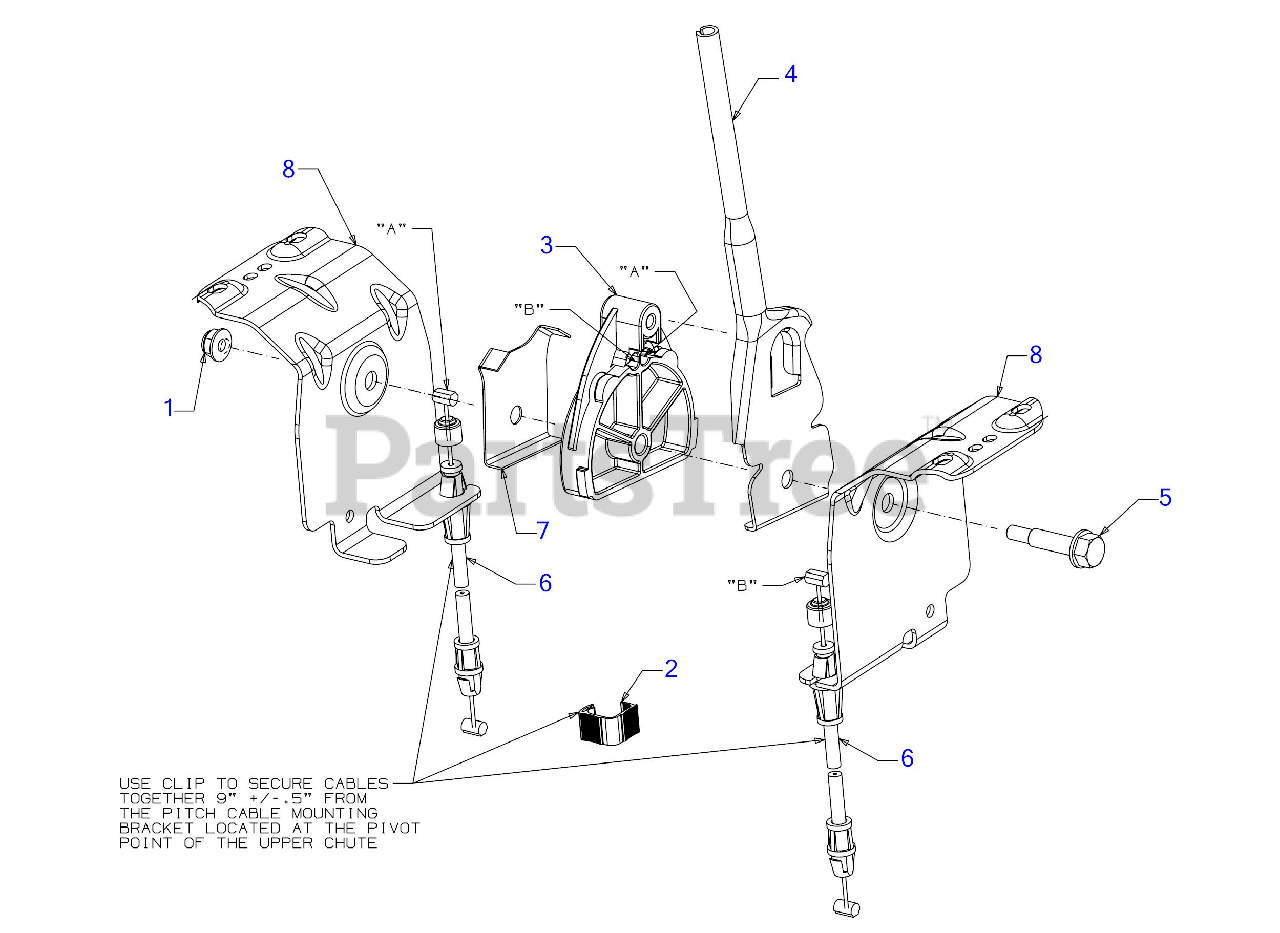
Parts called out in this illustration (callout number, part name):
1	FLANGE LOCK NUT
2	CABLE CLIP
3	CABLE GUIDE
4	SHIFT LEVER
5	SHOULDER SCREW
6	2-WAY PITCH CONTROL CABLE
7	CHUTE BRACKET GROUND
